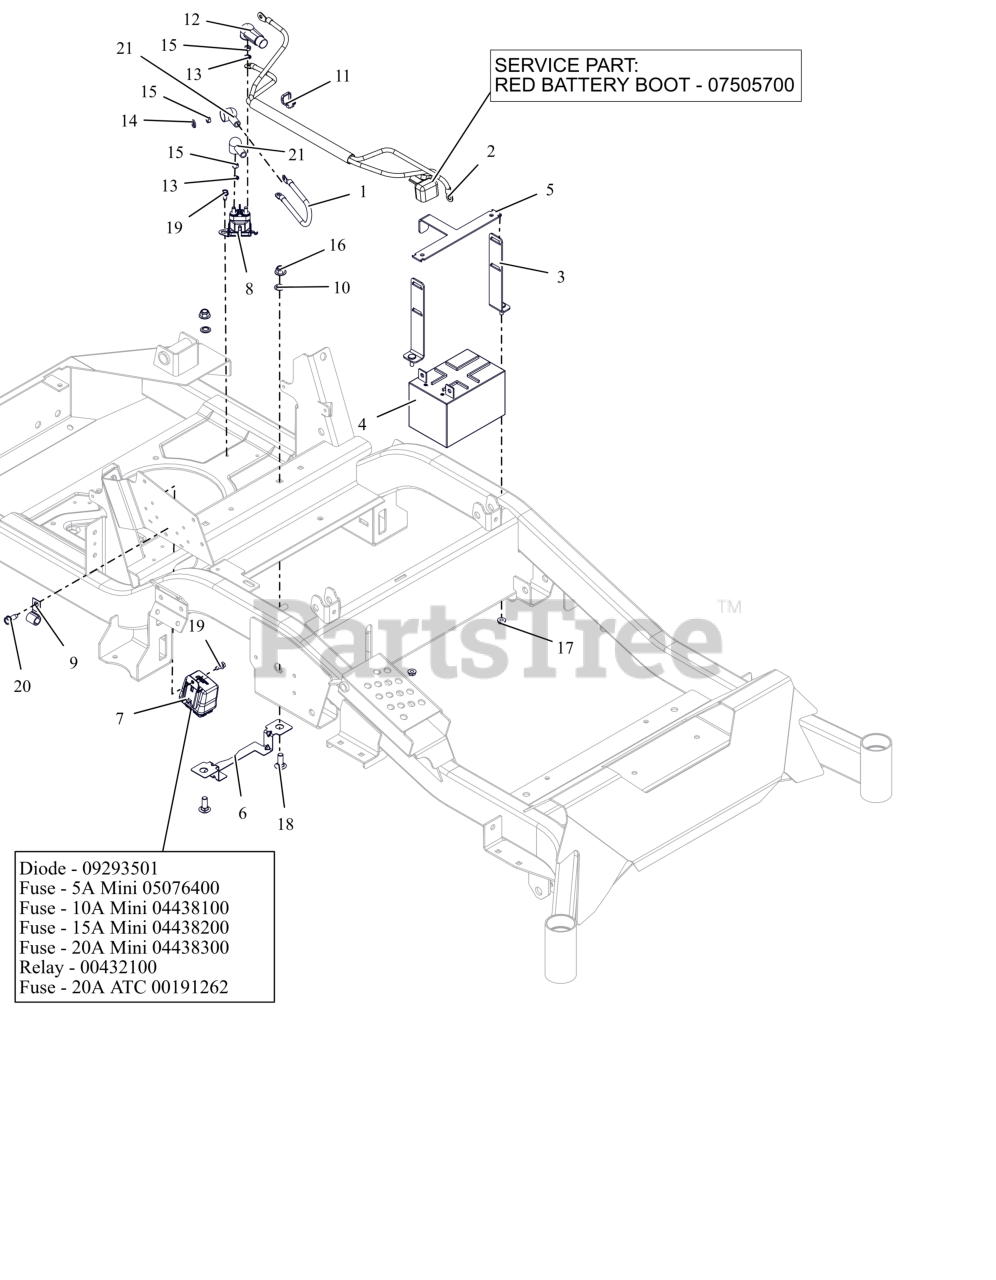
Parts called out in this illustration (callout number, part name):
1	CABLE, POS W/(2)1/4 RING 9.0LG
2	HARNESS, BATTERY HD
2	INSULATOR
3	WMT,BATTERY MOUNT HOLD DOWN
4	BATTERY, 12V 12A-190CCA
5	BRKT, BATTERY TIE DOWN
6	GUARD, ELECTRICAL HARNESS
7	HARNESS, WIRE
7	DIODE, CONNECTOR SHELL
7	FUSE, 5 AMP MINI-ATC
7	FUSE,10 AMP MINI-ATC
7	Fuse, 15 AMP MINI-ATC
7	FUSE,20 AMP MINI ATC
7	RELAY,SEALED W/DIODE
7	FUSE, 20 AMP BLADE S/O
8	SOLENOID, STARTER (SEALED)
9	J-CLAMP
10	NUT-PUSH .38 DIA. PAL ZINC
11	CABLE TIE W/ TREE (.25 HOLE)
12	BOOT, .65ID POS
13	WSHR,LK-EXT.262X.502X.026 ZCC
14	WSHR,LK-REG .312X.078 ZCC
15	NUT-STD M6-1.0 ZCC
16	NUT,NYL-FLG .38-16 GF ZCC
17	NUT-LK-TOP-FLG .250-20 GF ZCC
18	BLT, RHSN .38-16X1.00 G5 ZCC
19	SCR-TAP .25-20X.50 HWH ZCC
20	SCR,TAP .312-18X.75 HWH TR ZCC
21	BOOT, EYELET TERMINAL
